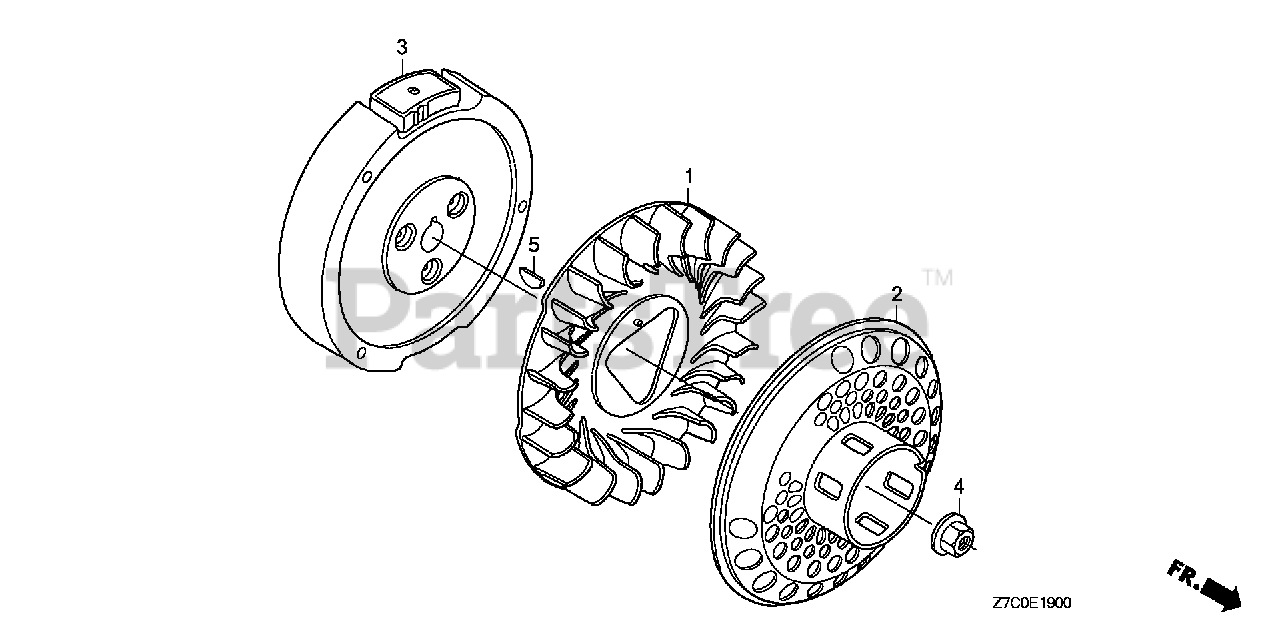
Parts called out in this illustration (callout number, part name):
1	FAN, COOLING
2	PULLEY, STARTER
4	NUT, SPECIAL (16MM)
5	KEY, SPECIAL WOODRUFF (25X18)
